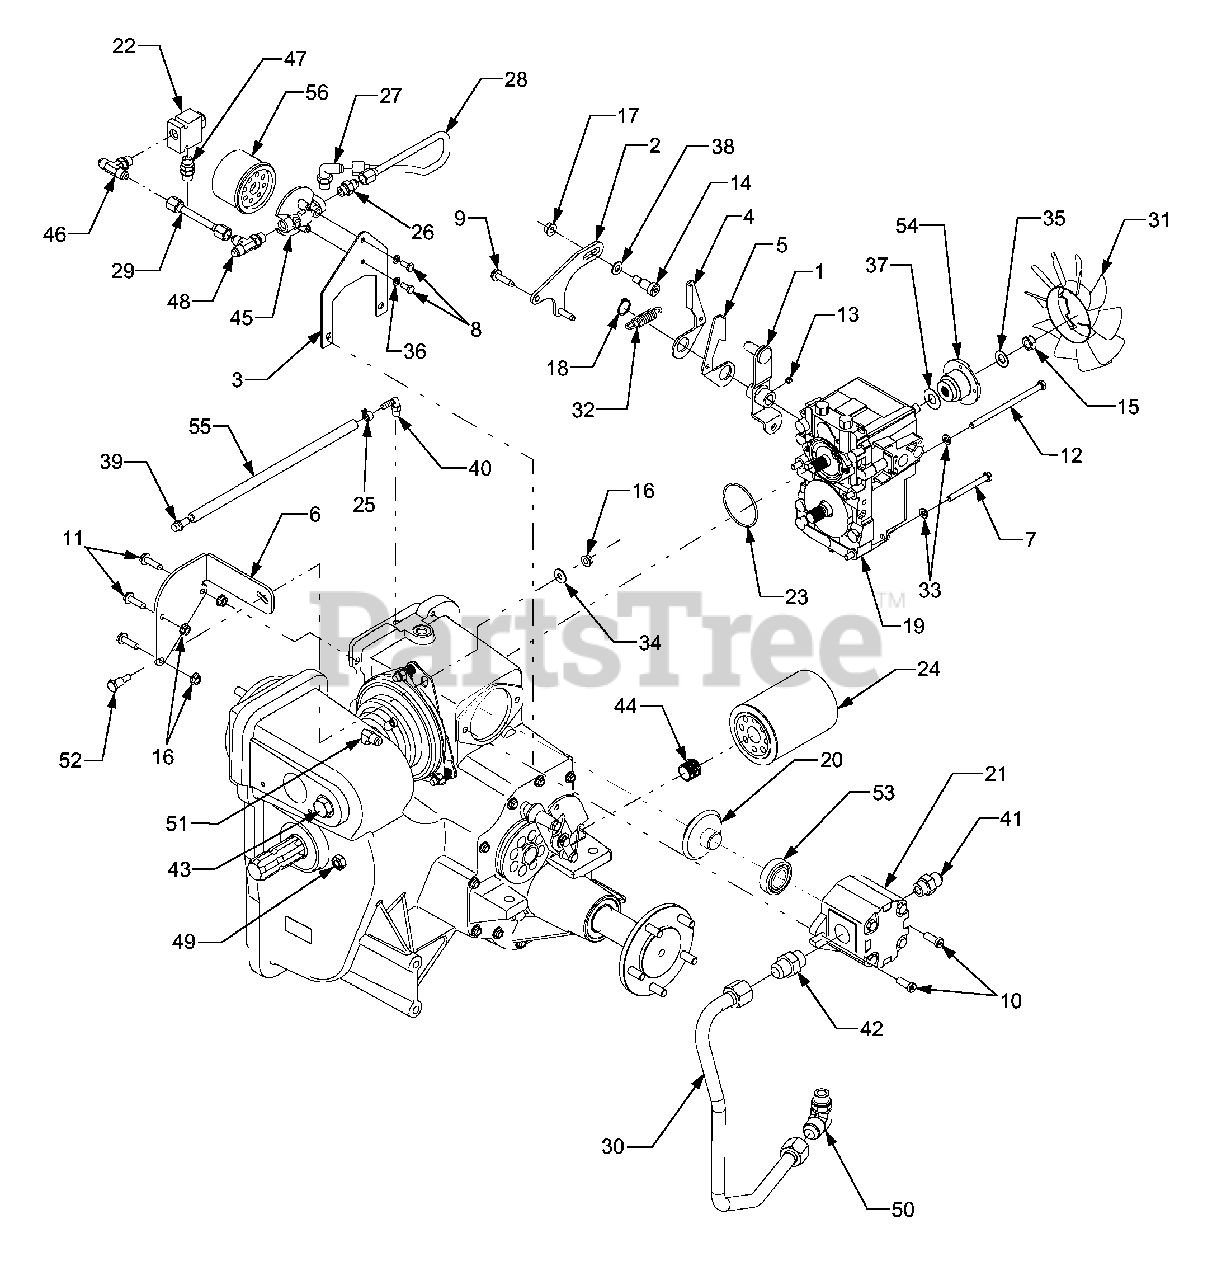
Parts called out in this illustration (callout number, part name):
1	Arm, Hydro
2	Bracket, Return
3	Bracket, Filter Mounting
4	Arm, Neutral - RH
5	Arm, Neutral - LH
6	Bracket, Clutch Torque
7	Screw, Hex Cap, 5/16-18 x 3.0 GR5
8	Screw, Hex Cap, 1/4-20 x .62 GR5
9	Screw, Hex Wash. Hd. Tapp, 5/16-18 x 1.25
10	Screw, Socket Hd. 3/8-16 x 1.0
11	Screw, Hex Flange, 5/16-18 x 1.5 GR5
12	Screw, Hex Cap Lock, 5/16-18 x 5.5 GR5
13	Screw, Set - Lock 5/16 x .5 GR5
14	Screw, Shoulder, .497 x .750: 3/8-16
15	Nut, Hex Patch Lock, 1/2-20
16	Nut, Hex Flange Lock, 5/16-18 GR5
17	Nut, Hex Flange Lock, 3/8-16
18	Ring, Retaining
19	Pump, Hydrostatic Transmission
20	Gear, Bevel, 35T
21	Pump, Auxiliary Hydraulic
22	Valve, Check
23	O-Ring, 2.425 ID x .103
24	Filter, Oil - Hydraulic System
25	Clamp, Hose
26	Fitting, Straight
27	Fitting, 90 Degree
28	Tube, Hydro Inlet
29	Tube, Filter Inlet
30	Tube, Aux. Pump Inlet
31	Fan, Transmission Cooling
32	Spring, Extension, .50 x 1.975 x.072
33	Washer, Lock, 5/16
34	Washer, Bell., .34 x .872 x .06
35	Washer, Belleville
36	Washer, Lock, 1/4
37	Washer, Flat, .56 x 1.0 x .04
38	Washer, Thrust, .375 x .812 x .06
39	Vent, 3/8 Dia
40	Fitting, Elbow
41	Fitting, Hyd. Adapter w/O-ring
42	Fitting, Hyd. Adapter w/O-ring
43	Fitting, Plug
44	Fitting, Filter Nipple
45	Adapter, Oil Filter
46	Fitting, Branch Tee
47	Fitting, Adapter
48	Fitting, Run Tee
49	Indicator, Oil Level Sight
50	Fitting, Elbow
51	Fitting, Elbow
52	Screw, Shoulder, .437 x .54
53	Bearing, Ball
54	Adapter, Hydro Pump
55	Hose, Vent
56	Filter, Hydro Pump
